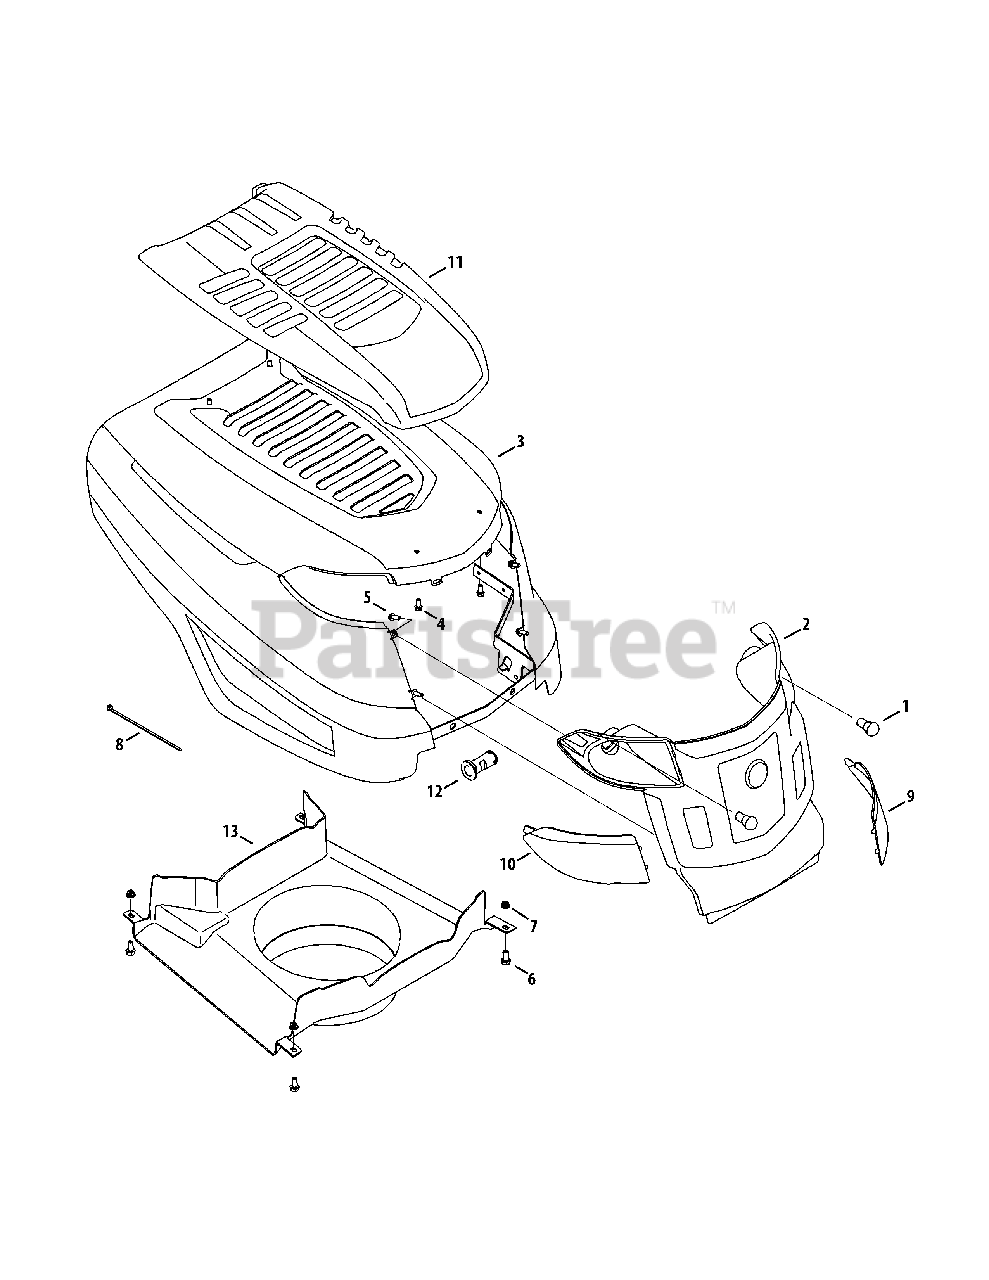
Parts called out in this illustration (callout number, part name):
1	Miniature lamp 12V socket
3	Hood Assembly
4	Screw, 1/4-15 x 0.50
5	Screw, 1/4-10 x .750
6	Hex Cap Screw, 1/4-20 x .62
7	Nut, Flange Lock, 1/4-20, Nylon
8	Cable Tie
9	Grill Lens - LH
10	Grill Lens - RH
13	Plenum
